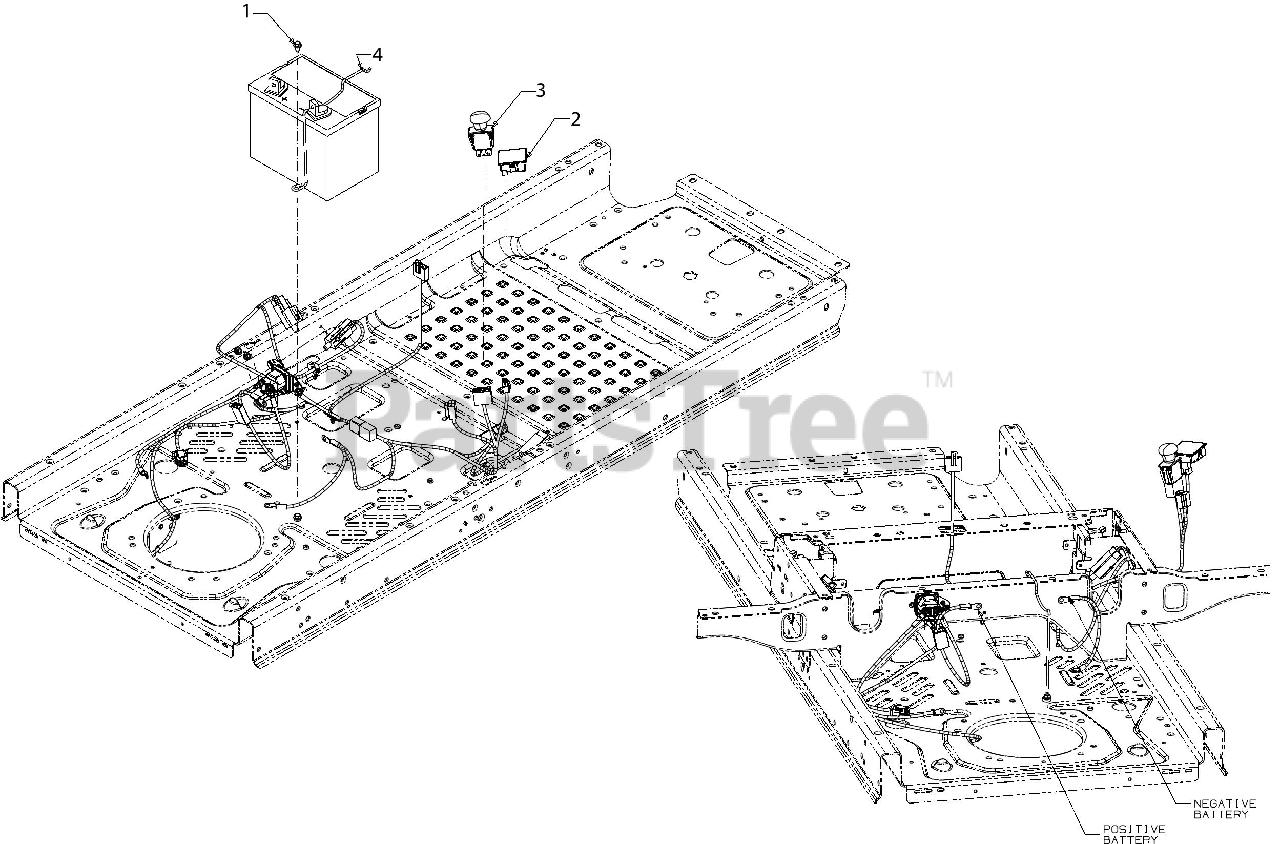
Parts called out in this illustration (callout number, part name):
1	SCREW 1/4-20X.625
2	HOUR/SVC METER
3	PTO SWITCH
4	BATTERY RETAINER
